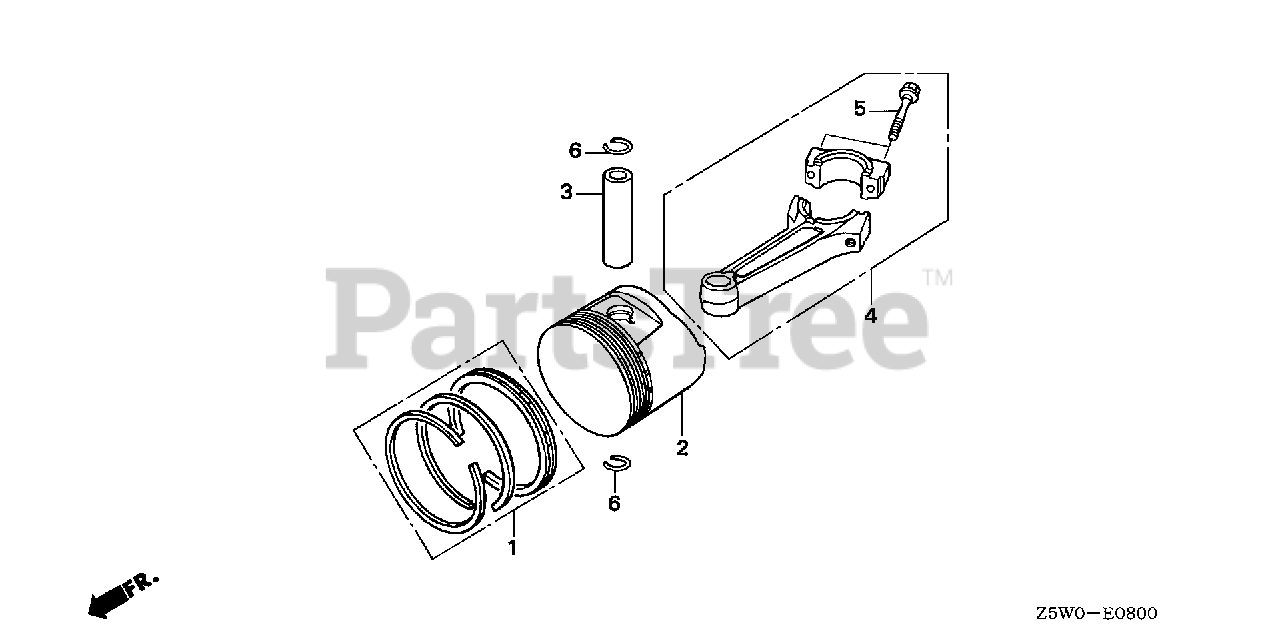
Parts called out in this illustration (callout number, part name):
1	RING SET, PISTON (STD) (RIKEN)
1	RING SET, PISTON (0.25) (RIKEN)
1	RING SET, PISTON (0.50) (RIKEN)
1	RING SET, PISTON (0.75) (RIKEN)
2	PISTON (STD)
2	PISTON (0.25)
2	PISTON (0.50)
2	PISTON (0.75)
3	PIN, PISTON
4	ROD ASSY., CONNECTING (STD)
4	ROD ASSY., CONNECTING (0.25 LOWER SIZE)
5	BOLT, CONNECTING ROD
6	CLIP, PISTON PIN (20MM)
